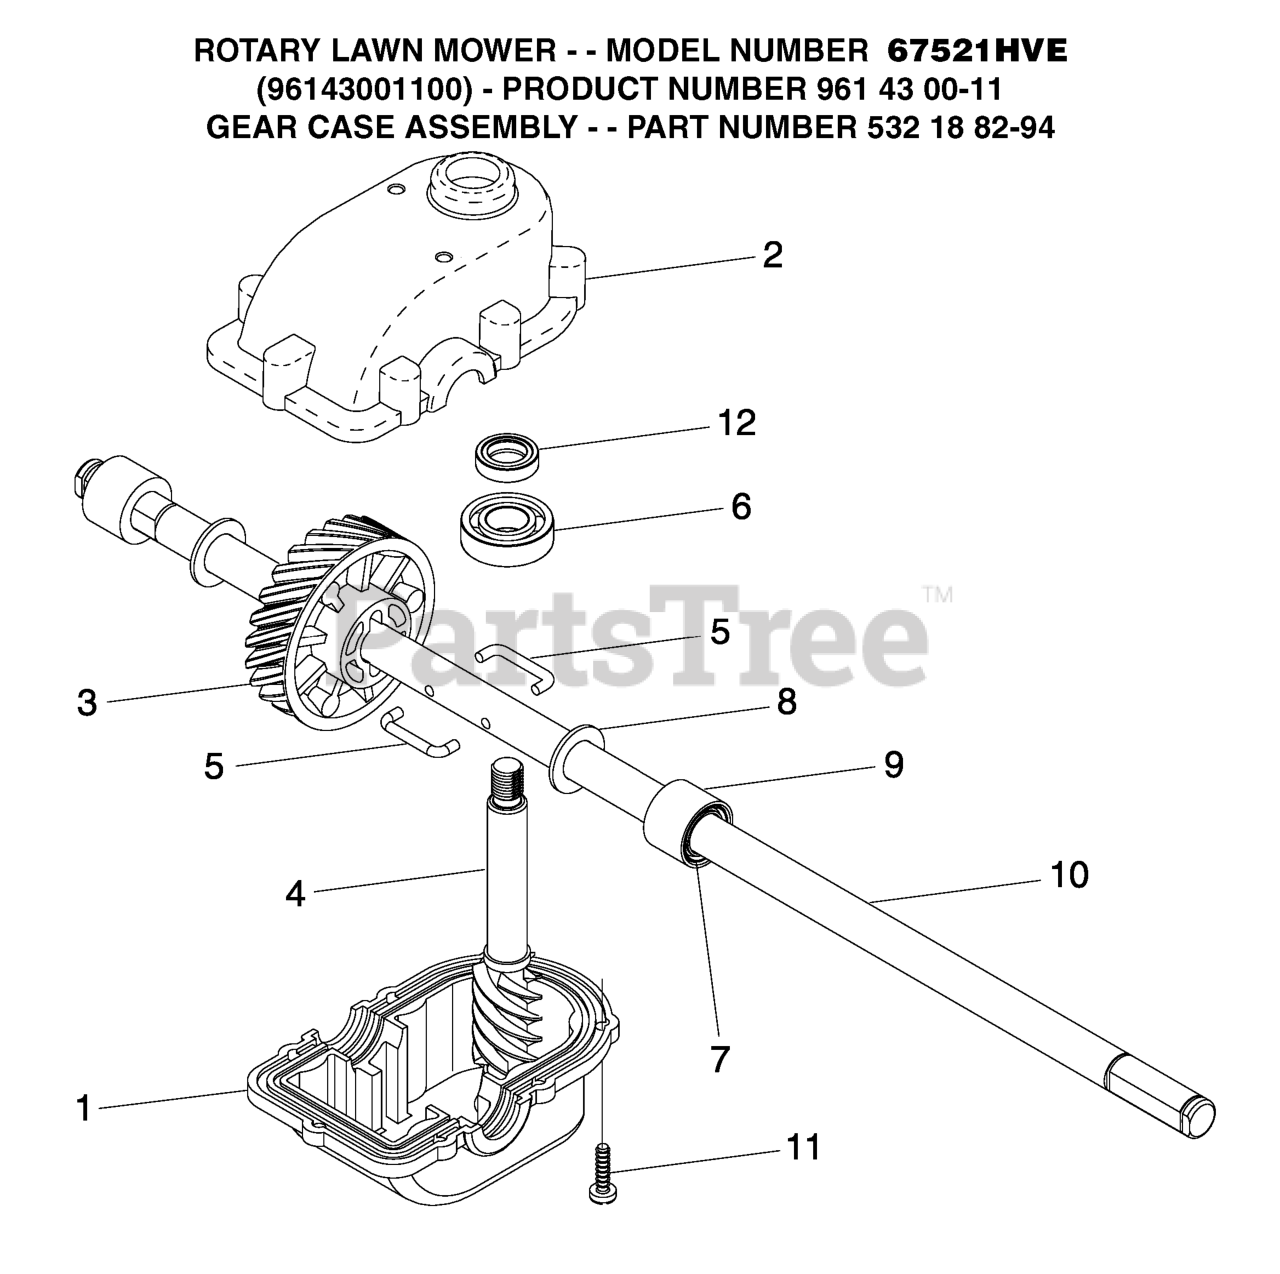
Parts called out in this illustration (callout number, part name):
1	CASE, LOWER
2	GEARCASE.HOUSING
3	GEAR.24.TOOTH.WALK.MOWER
5	WIRE, FORMED (15966)
7	SEAL.OUTPUT.SHAFT
10	SHAFT OUTPUT
12	SEAL INPUT SHAFT
